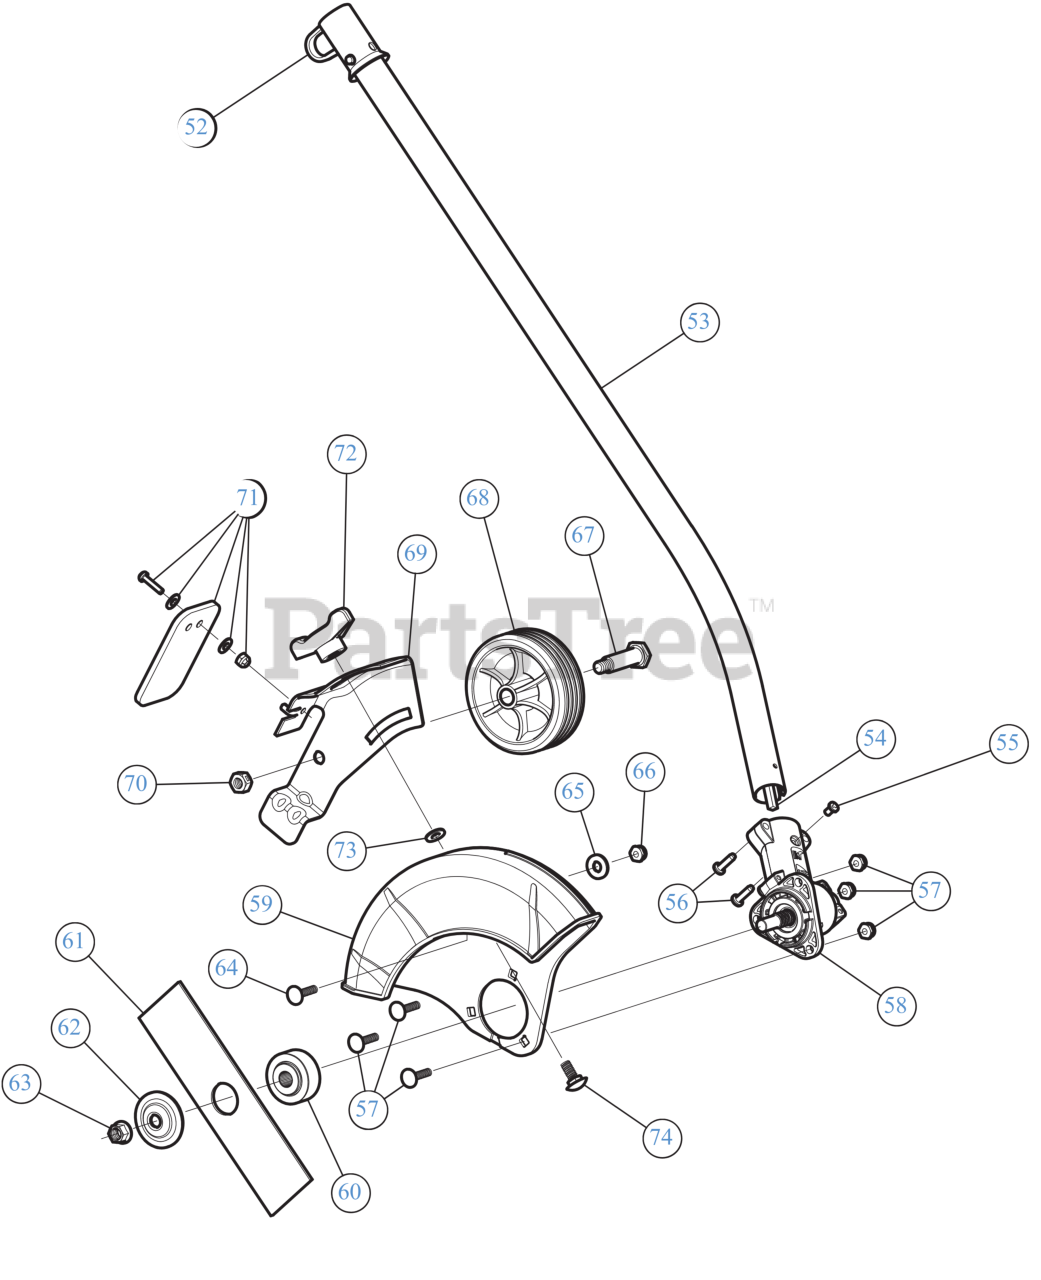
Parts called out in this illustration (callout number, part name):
53	BOOM ASSEMBLY LE
54	LOWER DRIVE SHAFT
55	SCREW, 8-32 x .312 P
57	HDWR ASM:GUARD MT
58	GRBX ASSEMBLY
61	EDGER BLADE
62	WASHER-BLADE CLAMP BRUSH CUT
63	BLADE LOCK NUT
64	BOLT:WHEEL MT BRACKET
65	FLAT WASHER
66	NUT 1/4-20 NYLOC
67	BOLT
68	WHEEL 3.75" (WHITE)
69	BRACKET GUARD
70	LOCK NUT 3/8-16
71	DEFLECTOR W/HDW
72	WING KNOB 5/16-18
73	WASHER .406X1.0X.095
74	CARRIAGE BOLT 5/16-18 x .75
